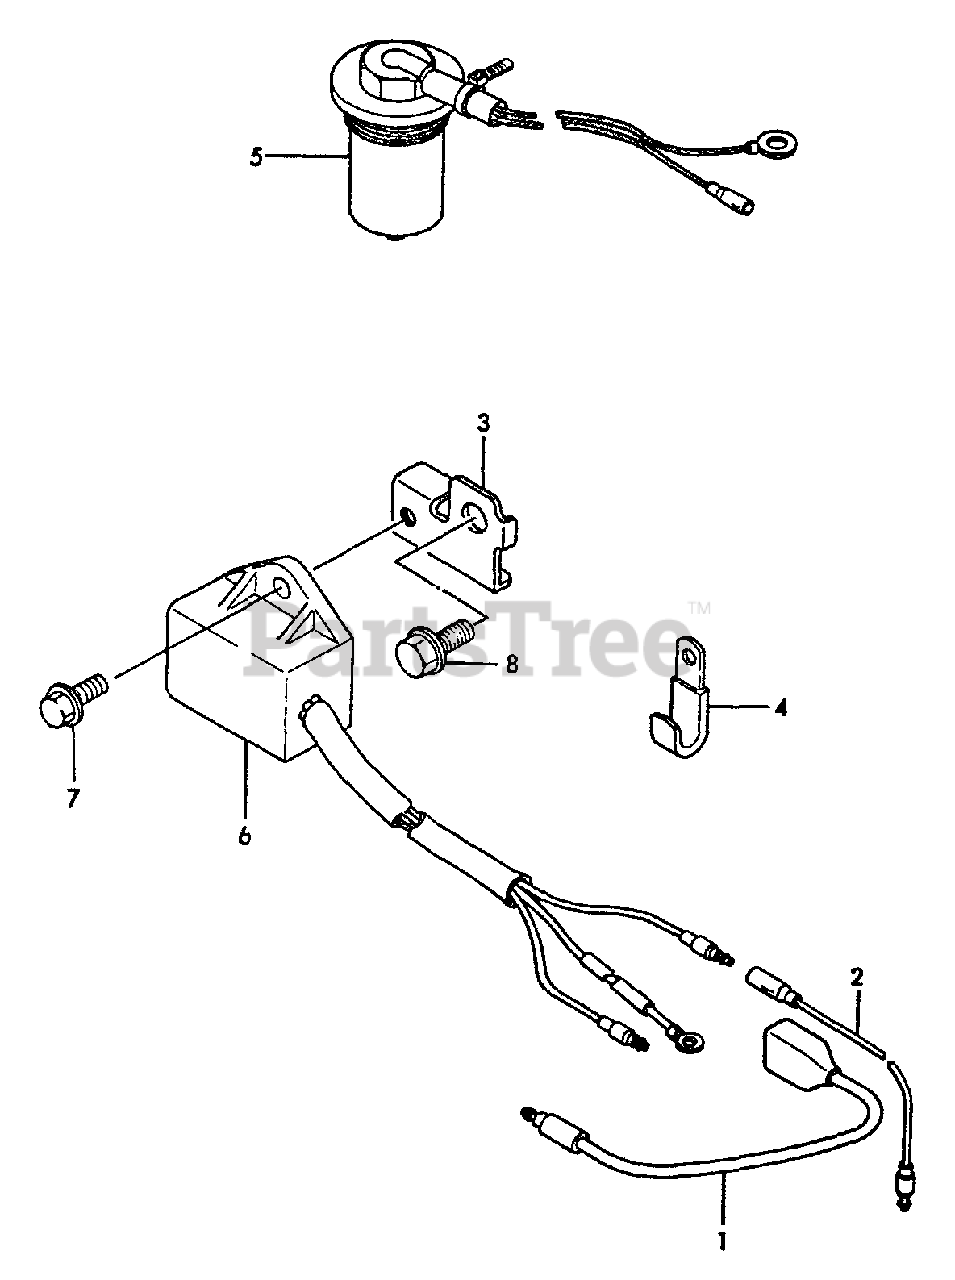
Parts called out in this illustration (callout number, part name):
1	WIRE
2	WIRE
3	STAY, SENSOR UNIT
4	CLAMP
5	SENSOR, OIL LEVEL
6	SENSOR UNIT
7	BOLT - 6×12 -- PLATED
8	BOLT - 8×14 -- PLATED
